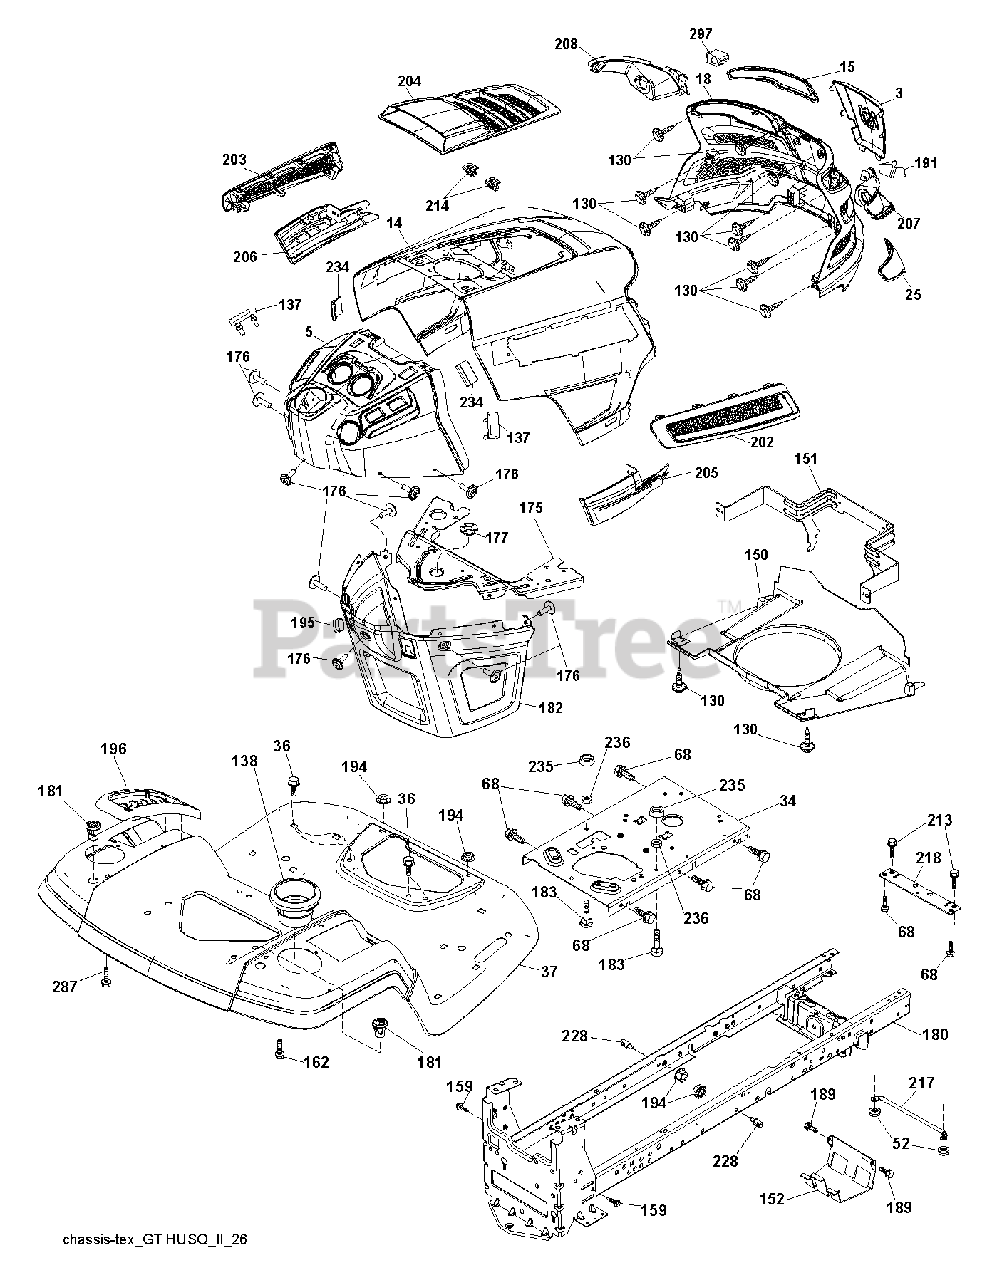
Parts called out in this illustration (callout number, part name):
3	APPLIQUE.SUBASM.GT.HUSQ.II
5	DASH.UPP.GT2.SM.MCLUTCH.CHOK
14	HOOD.ASM.HUSQVARNA.GT.TEX.422
15	LENS.HEADLIGHT.LH.GTII.2011
18	GRILLE.SUBASM.GT.HUSQ.II
25	LENS.HEADLIGHT.RH.GTII.2011
34	PLATE.ENGINE.WELDED.CHASSIS
36	SCREW 5/16"
37	FENDER
52	LOCKNUT
68	SCREW LT
130	SCREW.#10 X 0.750.BOS
137	BUMPER DASH
138	CUPHOLDER.TL.TEX.418
150	AIR DUCT.GTV2(1.66"RING HEIGHT
151	BRACKET.PIVOT.HOOD.GT.HUSQ.II
152	SHIELD.BROWNING.W/TEX
159	SCREW, 3/8-16X3/4
162	SCREW.HI-LO.CONSOLE
175	PLATE.CROSSMEMBER.HUSQ
176	SCREW.#10-24X5/8.RN.QU
177	BUSHING, STEERING
180	CHASSIS
181	BUSHING.MNT.FEND.CRGO.
182	DASH.LOWER.COMMON.12V.ADAPTOR
183	BOLT.5/16-18X1-1/4 FULL THD
189	SCREW
191	INSERT.REFLECTIVE.RH.HUSQ.GTII
194	NUT LOCK HEX FLANGE 5/16-18
195	PLUG.HOLE.DASH.LOWER.12V.BLK
196	RP CONSOLE.ASM.DECKLFT.GR/RBT.
202	VENT.SIDE.RH.GT.HUSQ.II.
203	VENT.SIDE.LH.GT.HUSQ.II.498
204	VENT.TOP.HUSQ.GT2
205	SIDE.TRIM.RH.GT.HUSQ.II
206	SIDE.TRIM.LH.GT.HUSQ.II.GRAY
207	BEZEL LIGHT.RH.GT.II.MYLAR
208	BEZEL LIGHT.LH.GT.II.MYLAR
213	BOLT
214	CLIP.RETAINER.TINNER.
217	ROD.PIVOT.HOOD
218	X-PIECE.HOOD.STOP.NON/
228	STUD.FASTNER.W/ANTI-ROTATE
234	BUMPER.HOOD.TEX.HUSQVARNA
235	SPACER FENDER
236	NUT.CENTERLOCK.5/16-
287	SCREW 1/4X20
297	INSERT.REFLECTIVE.LH.HUSQ.GTII
